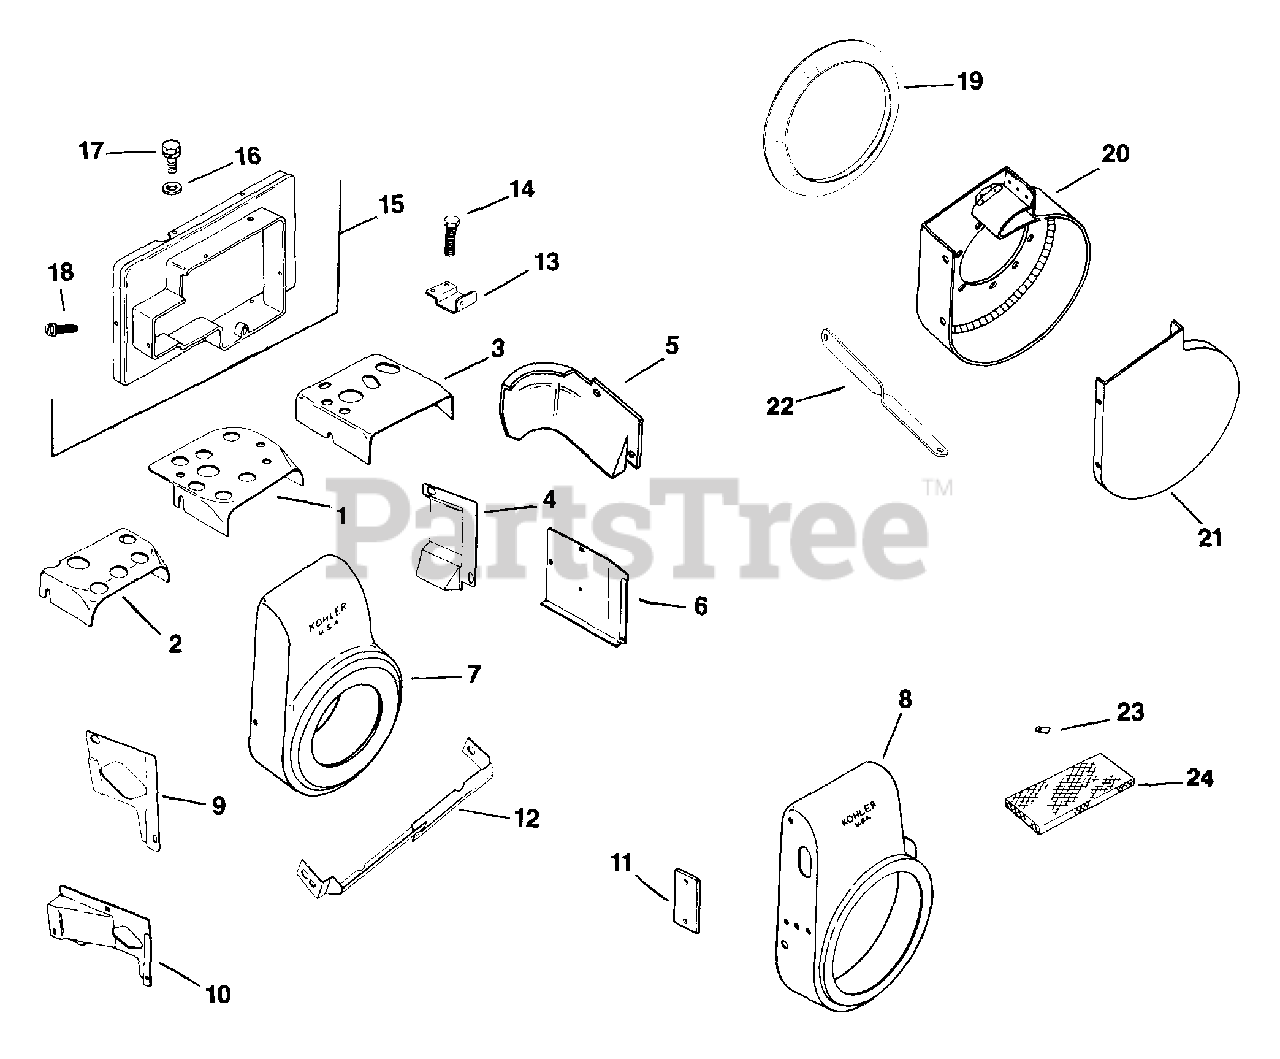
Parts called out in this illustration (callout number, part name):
2	BAFFLE, HEAD - (#DSC)
4	BAFFLE, CYLINDER
7	KIT, BLOWER HOUSING
9	BAFFLE, SIDE AIR
12	DEFLECTOR
